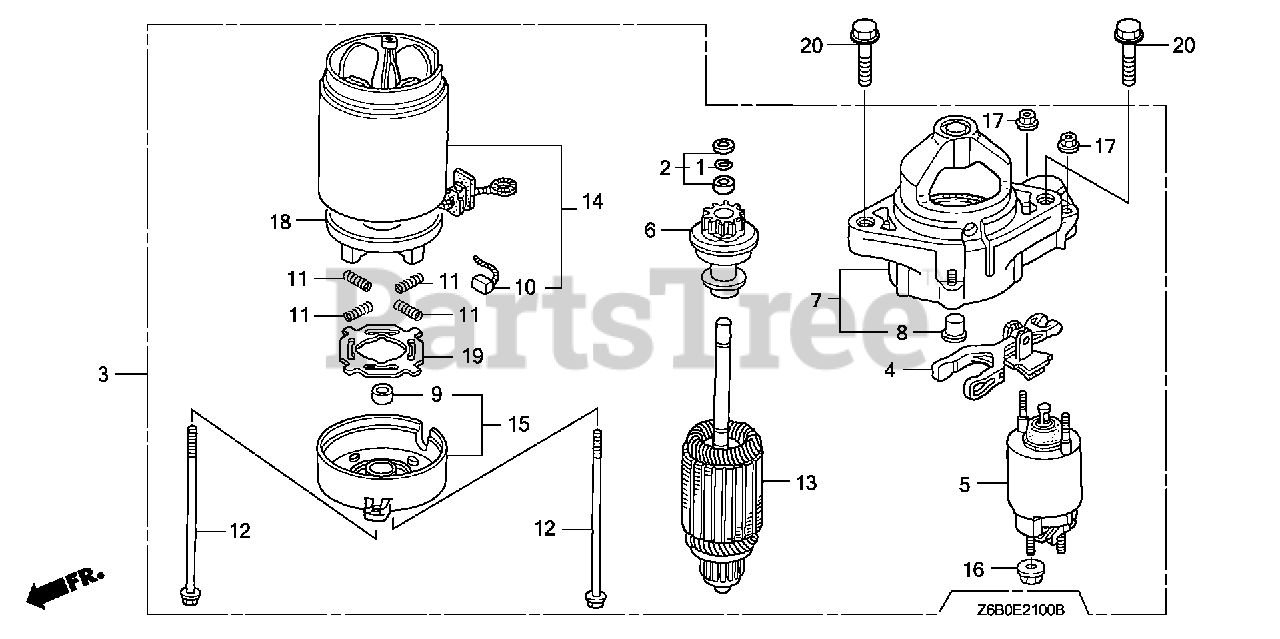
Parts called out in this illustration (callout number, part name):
1	RING, SNAP (DENSO)
2	COLLAR SET, CLUTCH STOP
3	STARTER MOTOR ASSY.
4	LEVER, PINION DRIVE
5	SWITCH ASSY., MAGNETIC
6	CLUTCH, OVERRUNNING
7	HOUSING, DRIVE SIDE
9	BEARING B
10	BRUSH
11	SPRING, BRUSH
12	BOLT, THROUGH
14	YOKE
15	FRAME, COMMUTATOR END
16	NUT, HEX. (8MM)
17	NUT, FLANGE (5MM)
18	HOLDER, BRUSH
19	INSULATOR, BRUSH HOLDER
20	BOLT, FLANGE (10X40)
